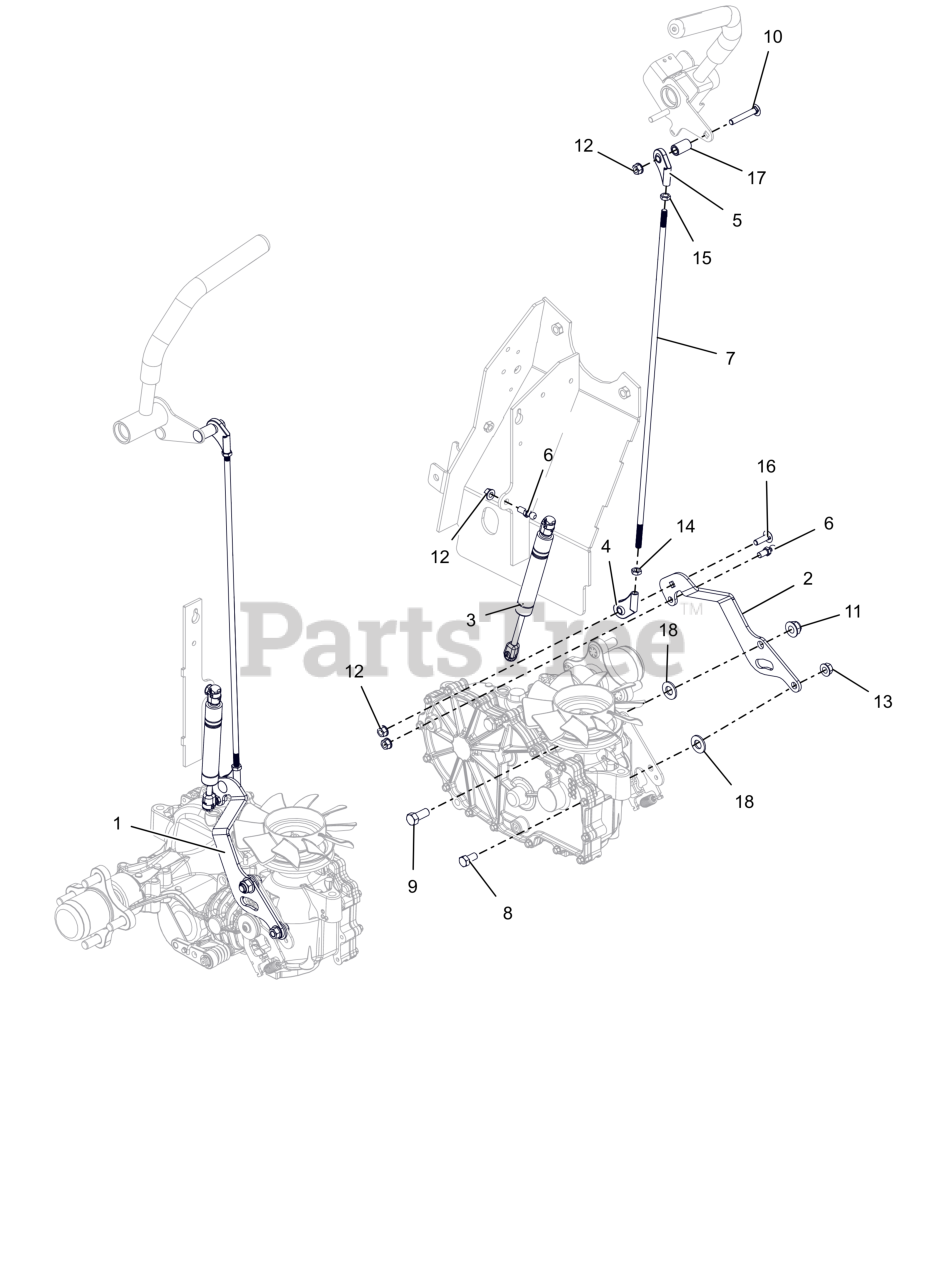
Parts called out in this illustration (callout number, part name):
1	ARM, RH 32-36" DRIVE CONTROL (BLACK)
2	ARM, LH 32-36" DRIVE CONTROL (BLACK)
3	DAMPER, CONTROL
4	END, ROD 5/16-24 RH
5	END, ROD 5/16-24 LH
6	STUD- BALL
7	ROD, STEERING
8	BLT,HEX .38-16X.75 G5 ZCC
9	BLT, HEX 0.4375-14X1 GR5 ZCC
10	BLT, RHSSN .31-18X2.00 G5 ZCC
11	NUT,NYL-FLG .44-14 GF ZCC
12	NUT,LK-CTR-FLG .31-18 GF ZCC
13	NUT-LK-CTR-FLG .375-16 GF ZCC
14	NUT-JAM .312-24 ZCC
15	NUT, JAM-LH .312-24 ZCC
16	BLT,RHSSN .31-18X1.00 G5 ZCC
17	SPACER, .375 X .625 X 1.063 PM
18	WSHR,FLT .531X1.062X.095 ZCC
